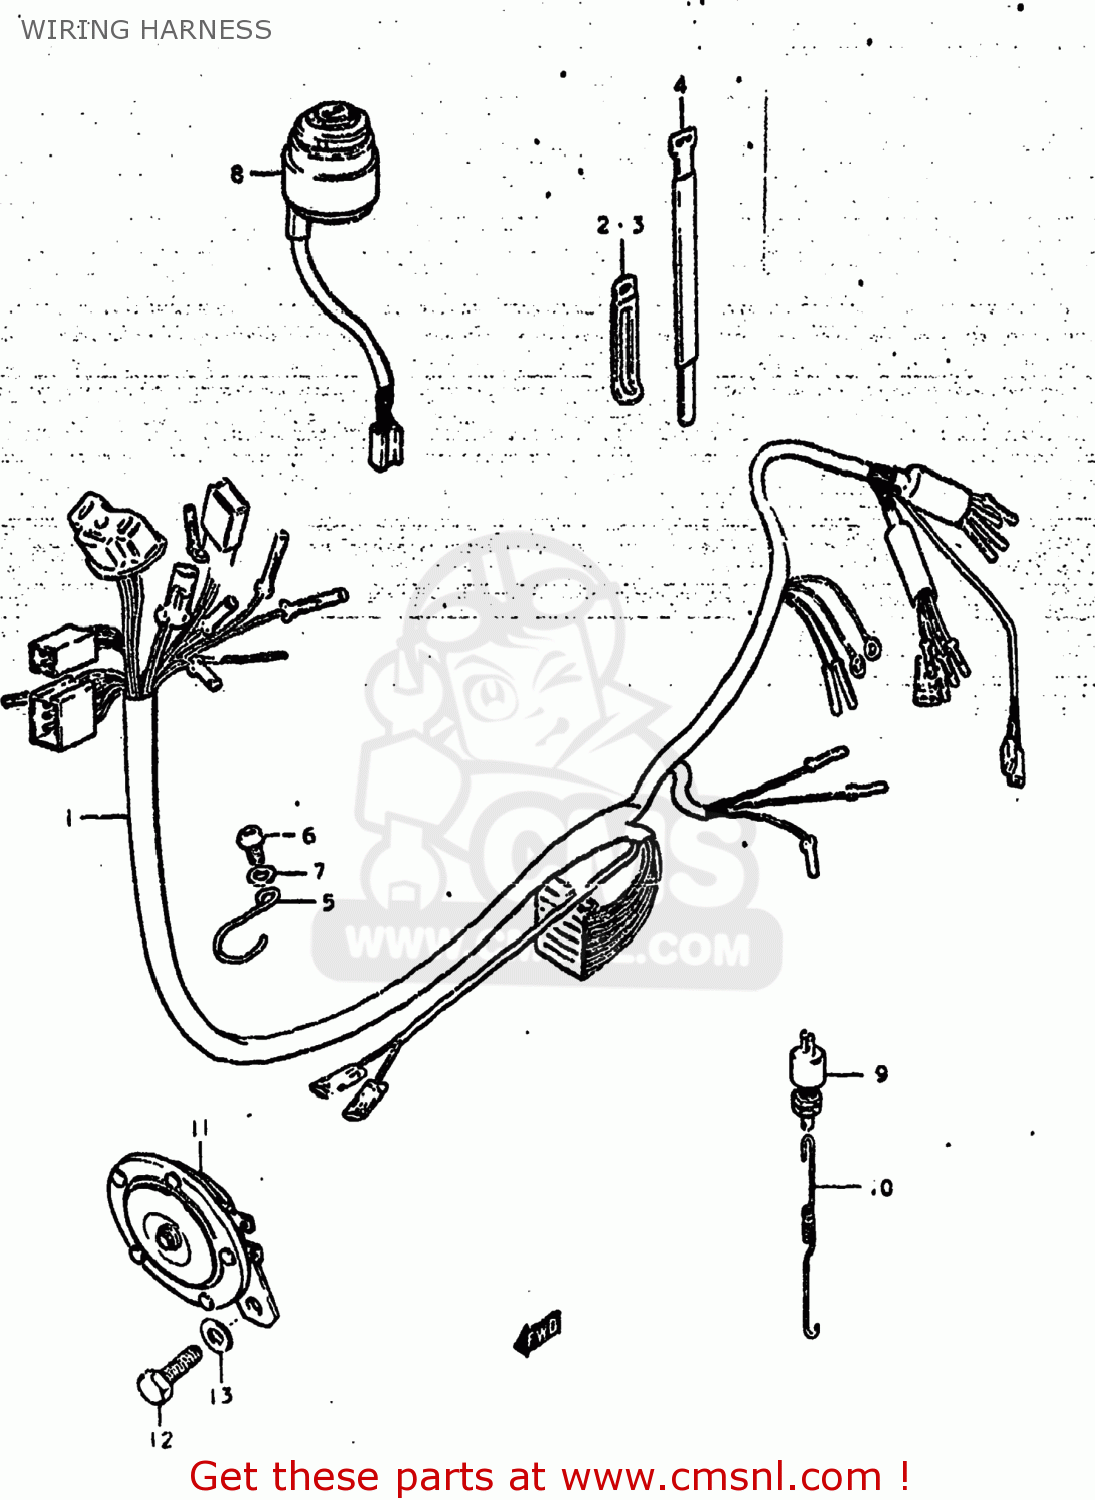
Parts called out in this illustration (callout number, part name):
1	HARNESS,WIRING
2	CLAMP
3	CLAMP
4	CLAMP
5	GUIDE,WIRING HARNESS
6	SCREW 6X12
7	WASHER 6MM
8	SWITCH ASSEMBLY,IGNITION
9	SWITCH ASSEMBLY,STOP LAMP
10	SPRING
11	HORN ASSY
12	BOLT 8X12
13	WASHER
